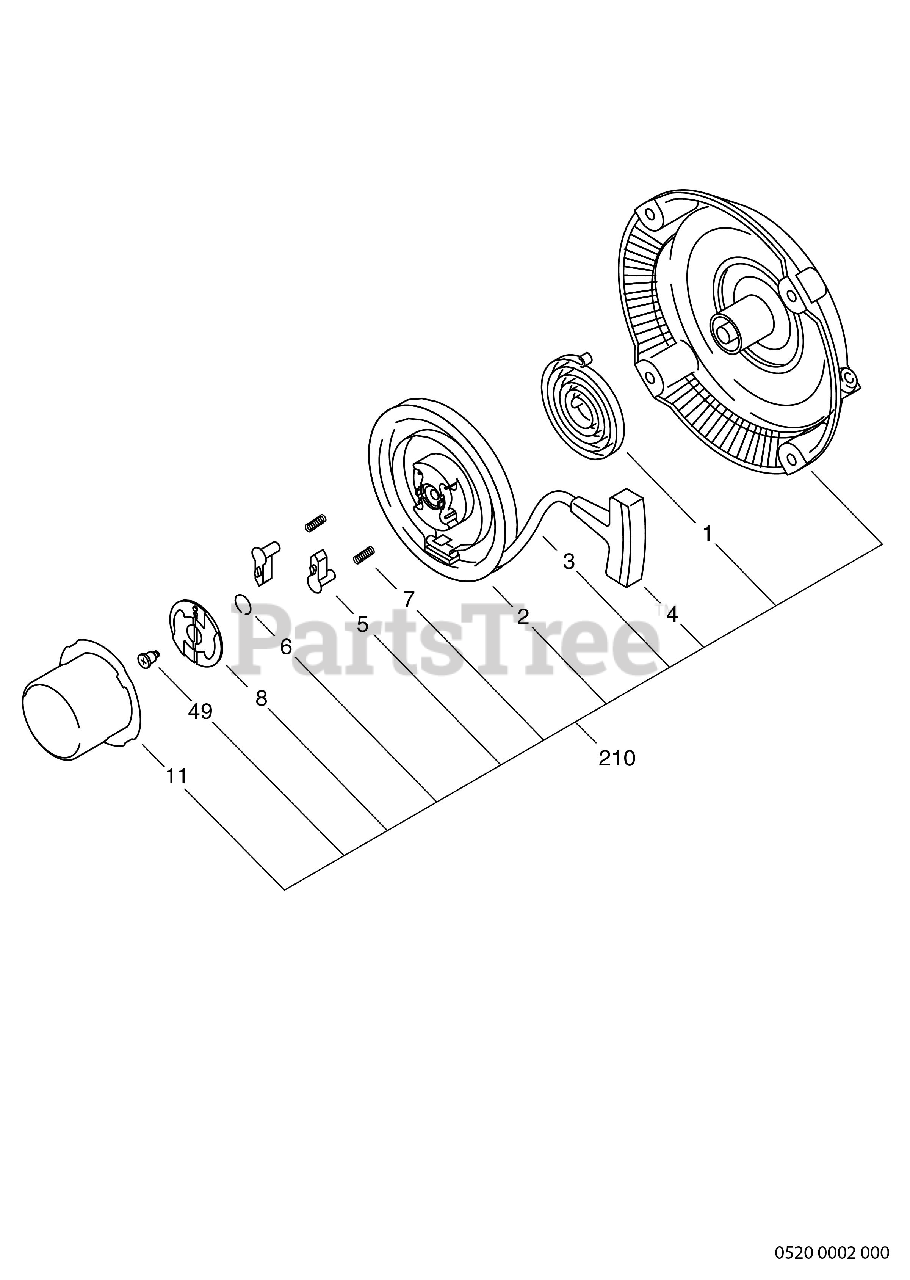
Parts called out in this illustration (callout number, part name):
6	FRICTION SPRING
8	FRICTION PLATE
11	STARTER PULLEY
210	RECOIL STARTER AY
